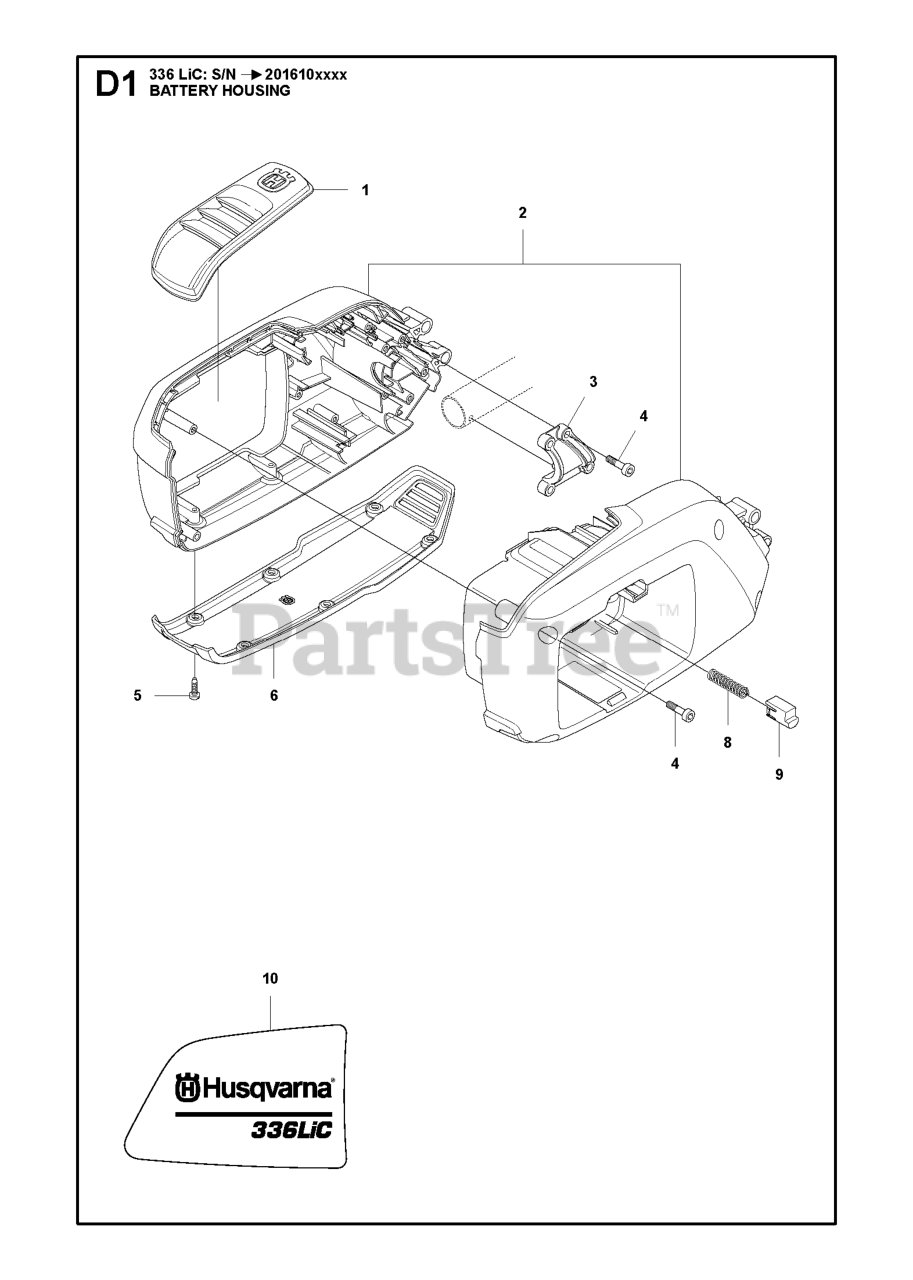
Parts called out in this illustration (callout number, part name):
1	CRANKSHAFT
2	BALL BEARING
3	NEEDLE BEARING PISTON PIN 12X1
4	NUT M8X1
4	WASHER 8.4X16
4	NUT W/ WASHER
